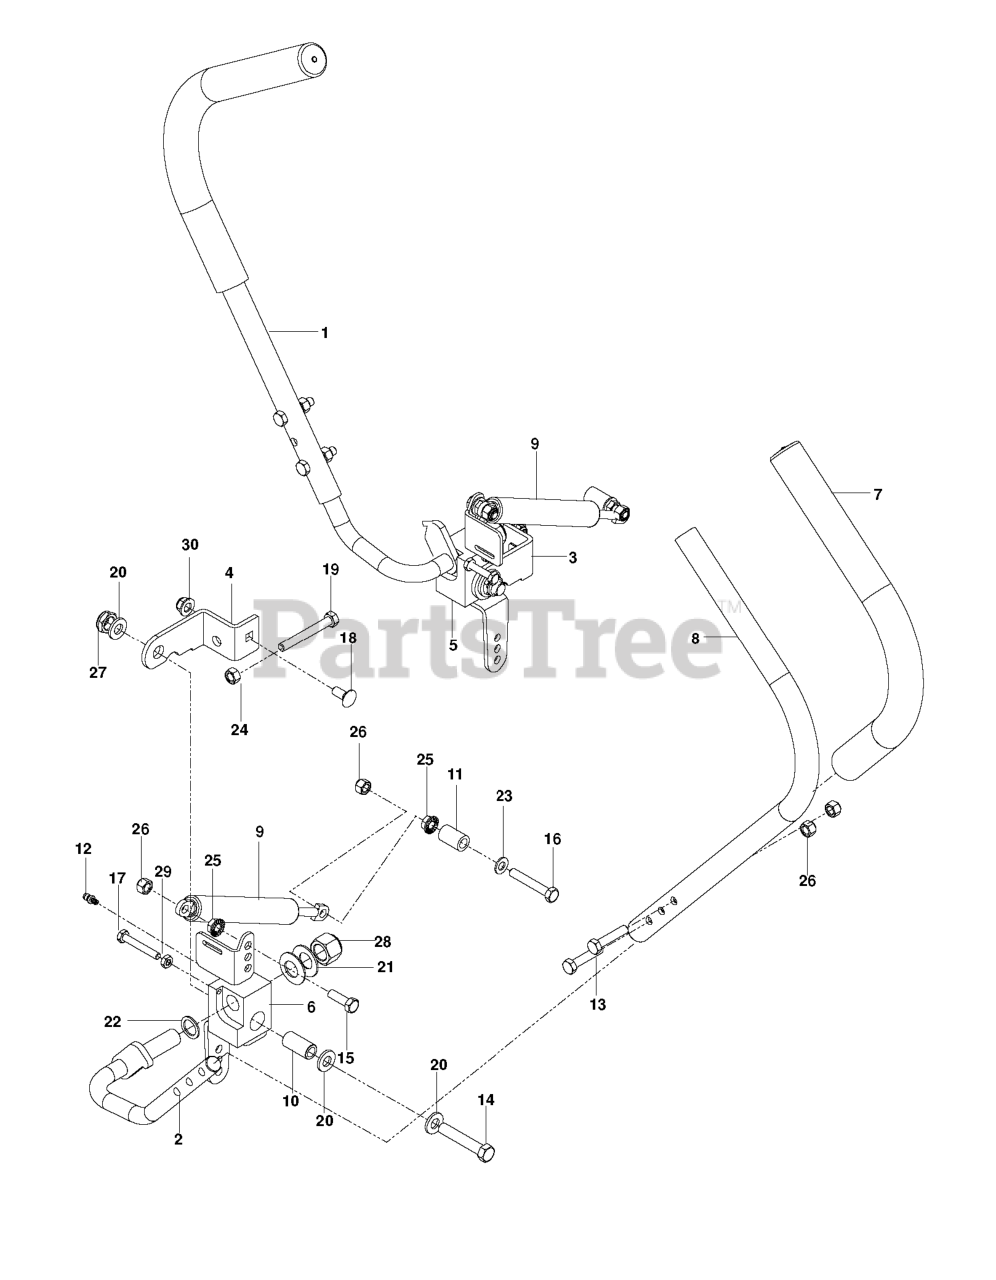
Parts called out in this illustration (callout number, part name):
1	LEVER.PLATED.RH
2	LEVER PLATED LH
3	FORWARD STOP RH
4	FORWARD STOP LH
5	PIVOT RH (PLATED)
6	PIVOT LH (PLATED)
8	LEVER UPPER
9	DAMPENER, DUAL ACTION
12	ZERK, 3/16, DRIVE IN
13	CAPSCREW 5/16 X 1/1/2 HEX HEAD
14	HCS 1/2C X 2 3/4
15	HCS 5/16C X 1
16	HCS 5/16-18X2
17	BOLT 1/4C X 1 3/4
18	BOLT 5/16C X 3/4" CARRIAGE
19	HCS 5/16-18 X 2 1/2 TPBLT
20	WASHER 1/2" FLAT
21	WASH 5/8 BEVELED DISC SPRING
22	WASHER-.626IDX.056TK
23	FLAT WASHER 5/16 SAE
24	NUT 5/16C HEX
25	NUT 5/16C WHIZ
26	NUT 5/16 NYLOC
27	NUT 1/2-13 HEX JM NYL
28	NUT 5/8-11 NYLOC
29	NUT 1/4-20 JAM
30	5/16-18 NYLOC FLANGE NUT
